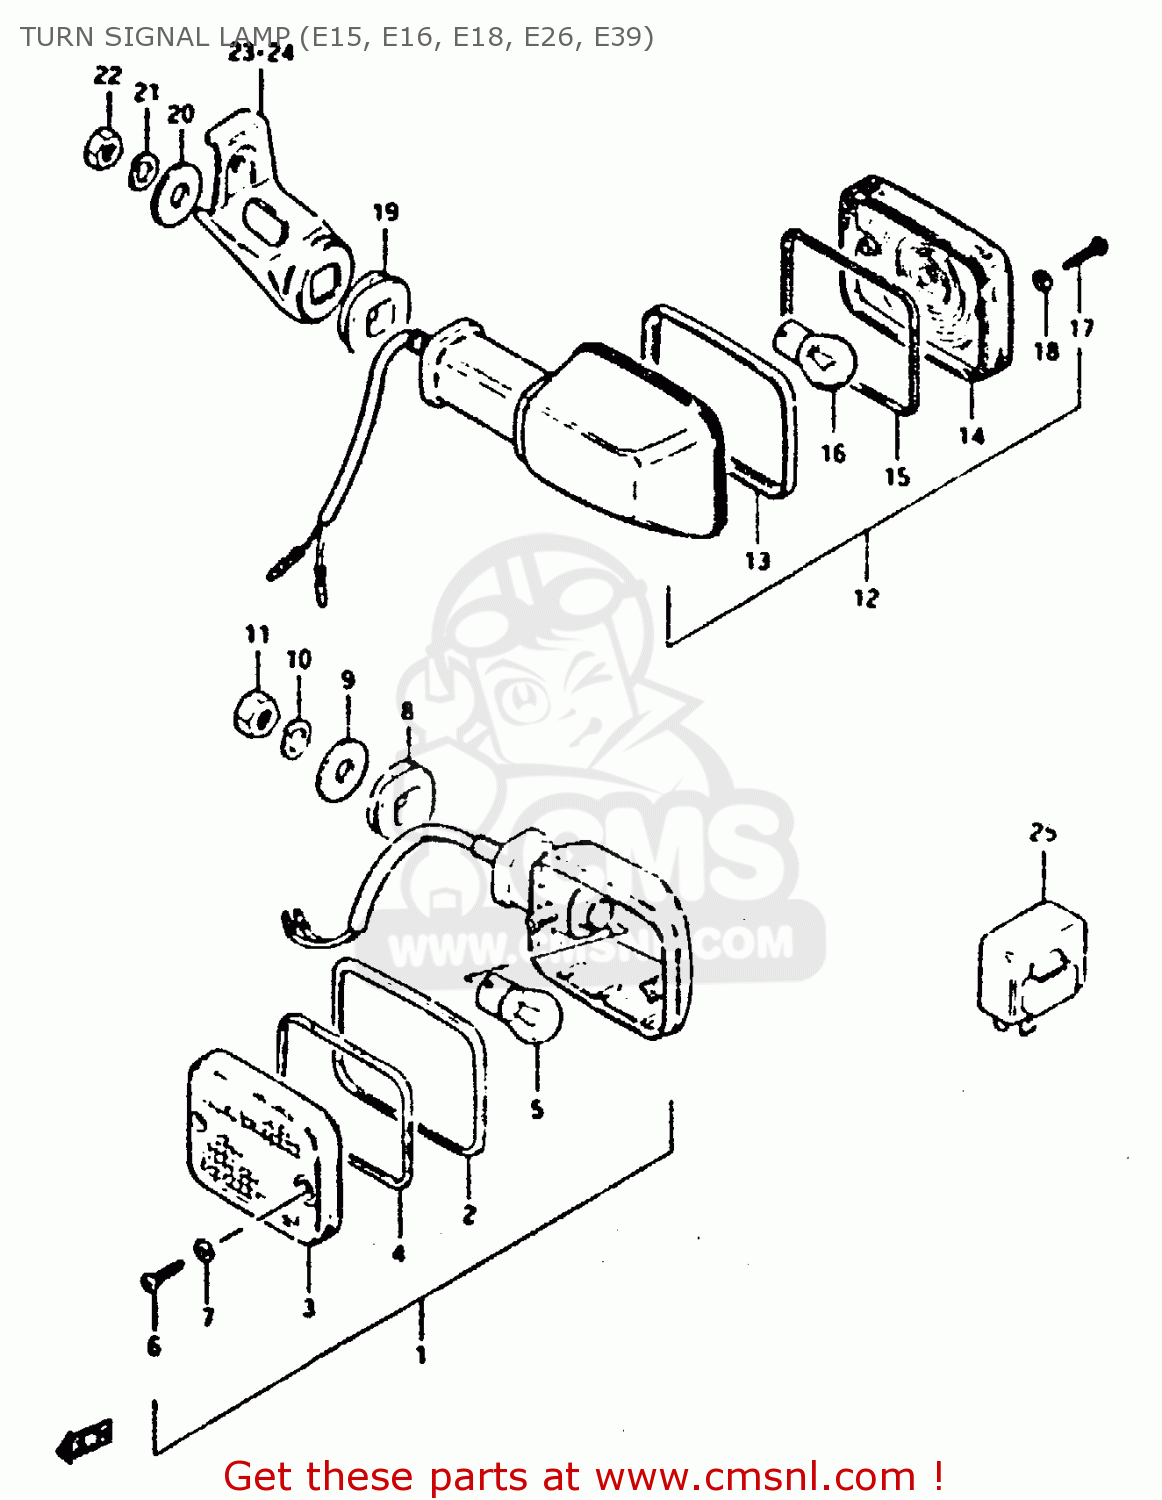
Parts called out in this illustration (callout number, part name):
1	LAMP ASSY,FR T
2	RIM
3	LENS
4	GASKET (NAS)
5	BULB 12V 21W
6	SCREW
7	GASKET (NAS)
8	CUSHION
9	WASHER (10.5X30X2.3)
10	LOCK WASHER
11	NUT
12	LAMP ASSY,RR T
13	RIM
14	LENS
15	GASKET (NAS)
16	BULB 12V 21W
17	SCREW
18	GASKET (NAS)
19	CUSHION
20	WASHER (10.5X30X2.3)
21	LOCK WASHER
22	NUT
23	BRACKET,REAR TURN SIGNAL
24	BRACKET,REAR TURN SIGNAL
25	RELAY,TURN SIGNAL
